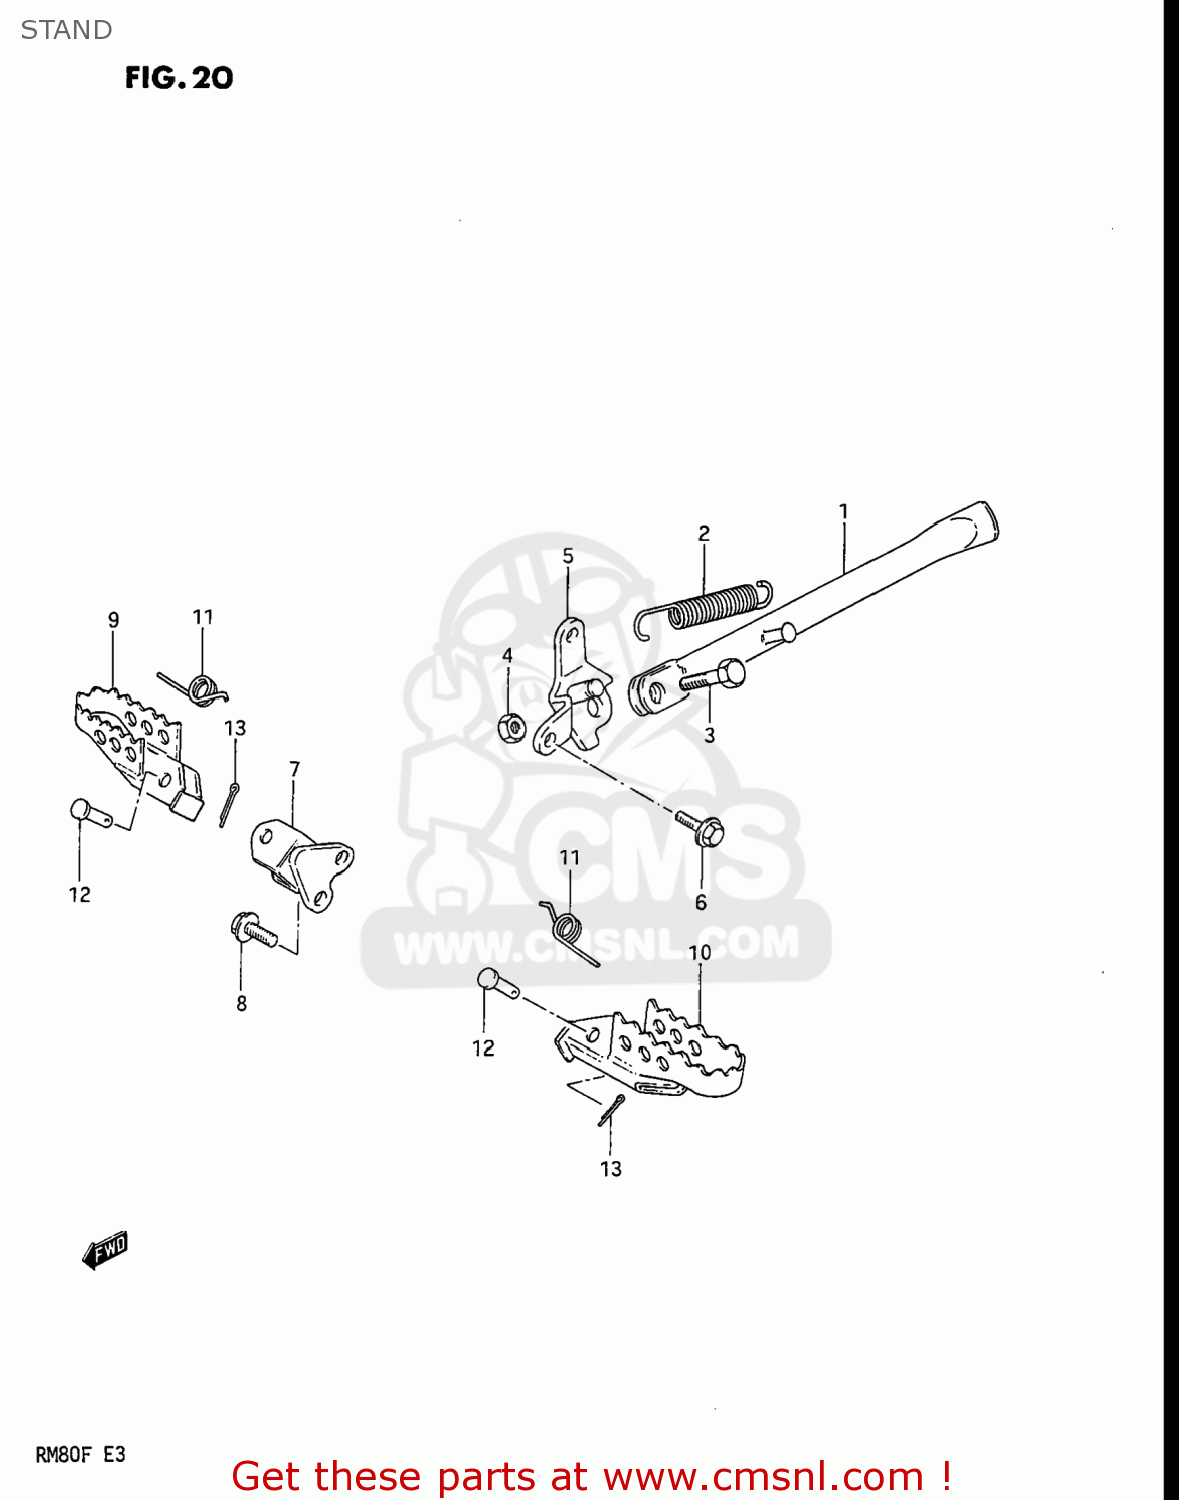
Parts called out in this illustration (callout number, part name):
1	STAND,SIDE
2	SPRING
3	BOLT
4	NUT
5	BRACKET,SIDE STAND
6	BOLT
7	BAR,FRONT FOOTREST
8	BOLT
9	FOOTREST,FRONT,RIGHT
10	FOOTREST,FRONT,LEFT
11	SPRING
12	PIN
13	PIN 20X20
